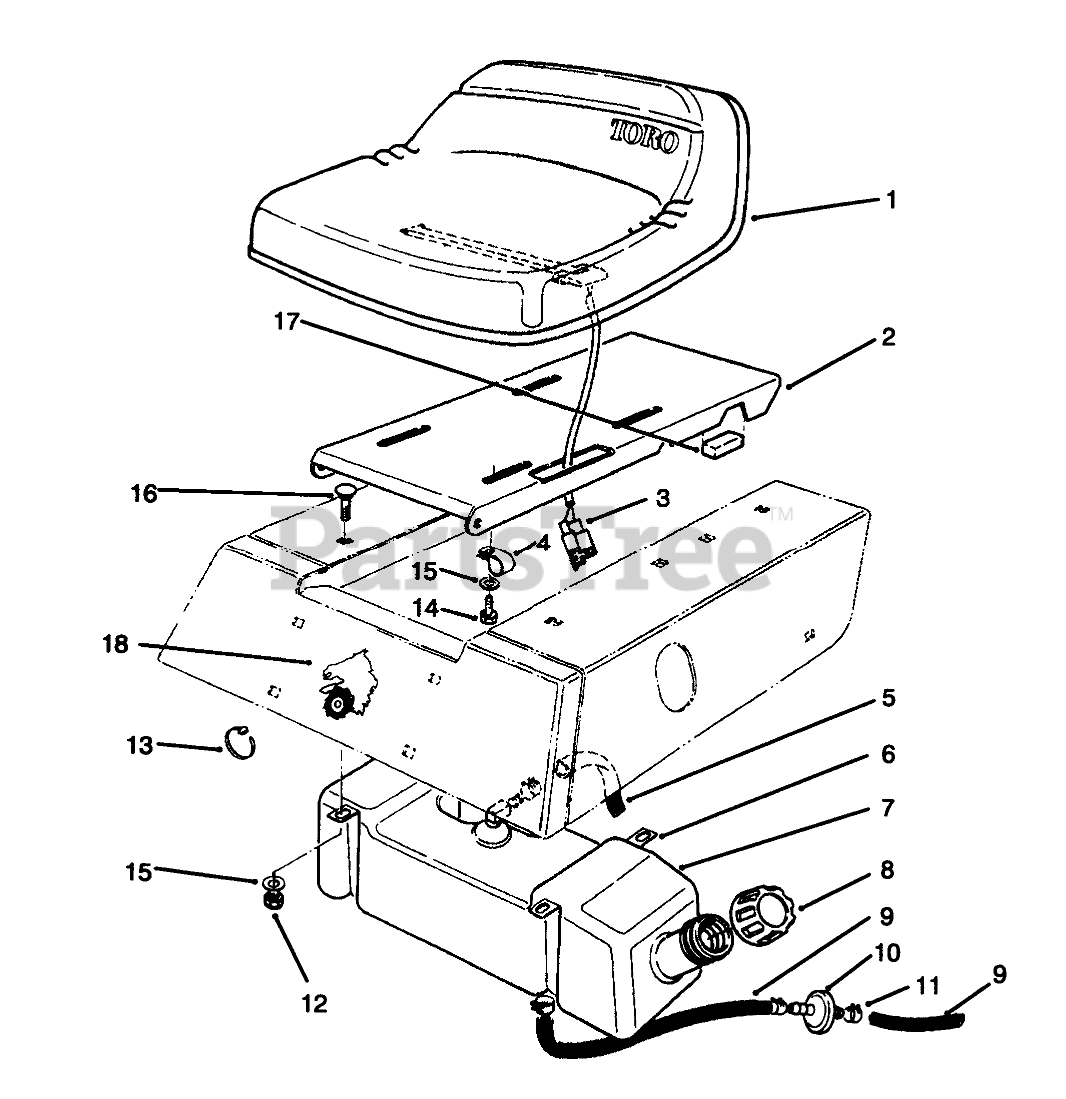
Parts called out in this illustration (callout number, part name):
2	BASE - SEAT
3	SWITCH-SEAT
4	CLIP-FUEL LINE
5	HOSE-FUEL
6	STRAP-GAS TANK
7	TANK-GAS
8	GAS CAP ASM
9	HOSE-FUEL
10	FILTER-FUEL
11	CLAMP-HOSE
12	NUT-LOCK, NI
13	TIE-CABLE
14	SCREW-HH
15	WASHER-PLAIN
16	SCREW-CARR
17	PAD-ISOLATOR
18	DECAL - W.H. INSIGNA
